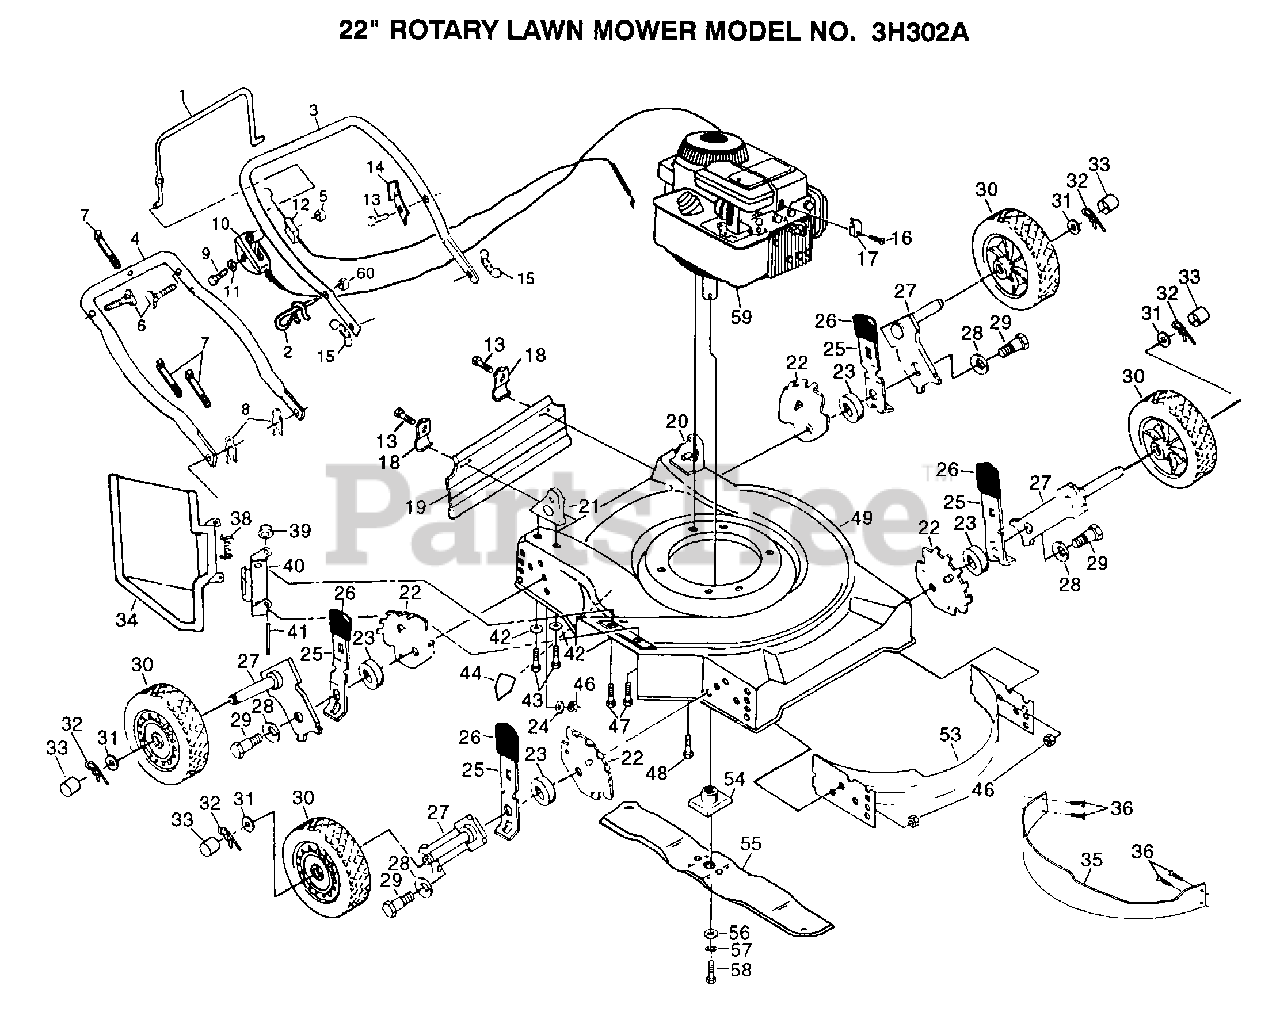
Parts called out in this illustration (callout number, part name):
1	CONTROL BAR
2	ROPE GUIDE
6	BOLT.HANDLE.LM
8	HAIRPIN COTTER
10	CNTL.THROT.47.5
11	WASHER PM
12	"CABLE,ENG ZONE CO"
13	TAPPING SCREW
14	"BRKT,UPSTOP"
15	"NUT,WING PM"
16	SCREW PM
17	CABLE CLAMP
18	"BRKT,DEFL PM"
25	SPRING SELECTOR
26	KNOB PM
27	AXLE ARM
28	"WASHER, BELLEVIL."
31	WASHER
32	RETAINER CLIP PM
33	HUB CAP
35	BAFFLE.MULCH.22SD
36	UNDCT OVRHD SCREW
38	"SPRING,TORSION"
39	PUSH ON SPEED NUT
40	"BRKT,HSG"
41	"ROD,HINGE "
42	STEEL WASHER
43	SCREW
44	DECAL HYT
46	LOCKNUT PM
47	SCREW
48	SCREW
49	KIT.HSG.22SD.PUSH
53	BAFFLE.FRT/REAR
54	BLADE ADAPTOR
56	"WASHER,HARDEN"
57	LOCKWASHER
58	SCREW
60	NUT
